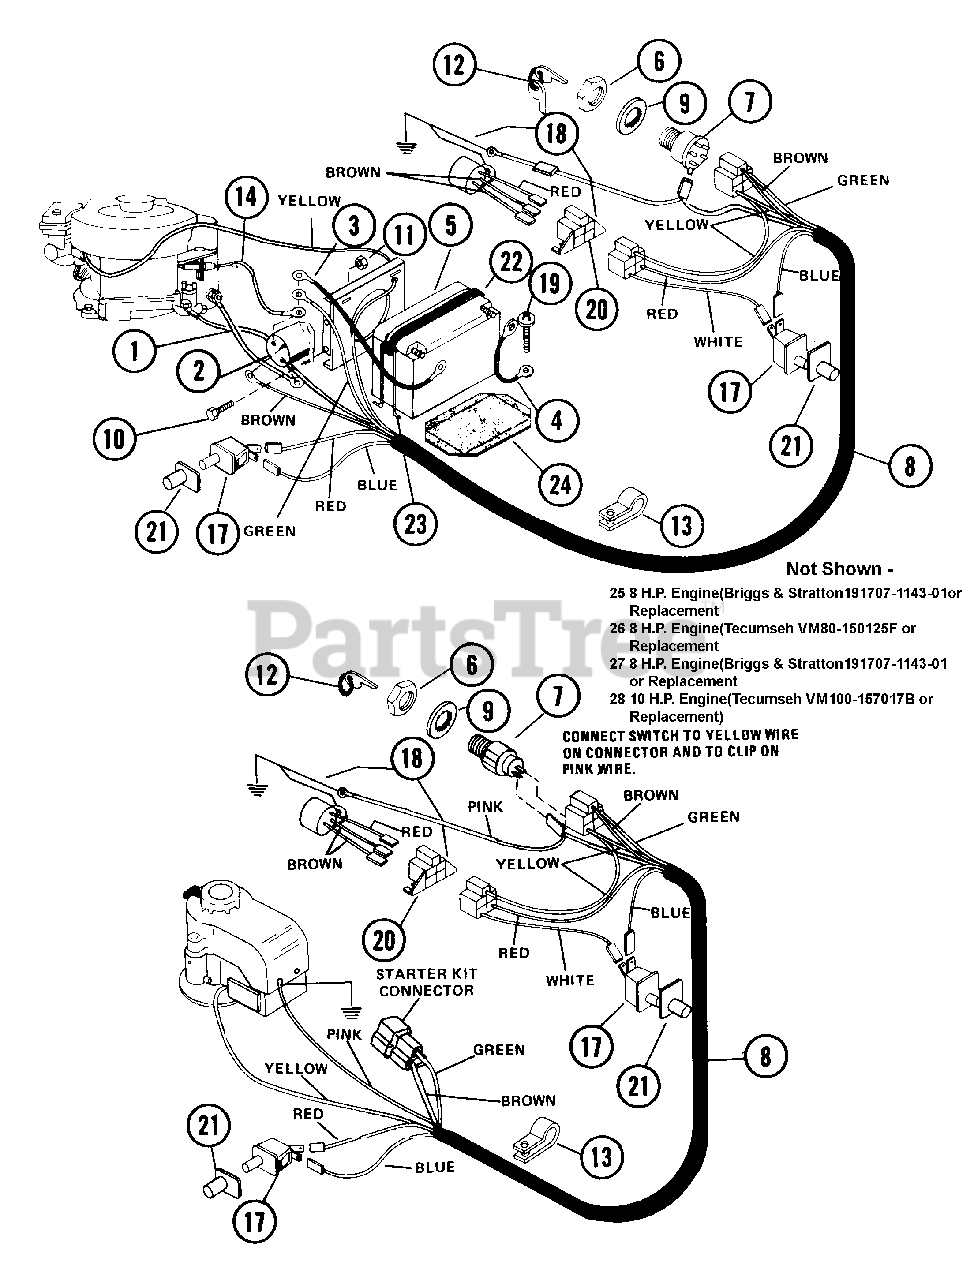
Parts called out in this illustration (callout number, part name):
1	GROUND CABLE .25X13.00X.31
2	SOLENOID,STARTER SWITCH
3	GROUND CABLE
4	GROUND WIRE
5	BATTERY
6	NUT .625-32 ALUM
7	IGNITION SWITCH ASSEMBLY
7	KEY SWITCH
8	WIRING HARNESS
8	WIRING HARNESS-B&S
9	WSHR-LK-INT .625X.045 PL
10	BLT-HEX .25-20X.50 PL GR2
11	NUT-LK-CTR .250-20 PL
12	KEYS
14	CHARGING WIRE
15	FUSE
18	MODULE T KIT
18	MODULE B KIT
19	SCR-TAP 10-24X.375 CRPH 1A
20	CONNECTOR
21	SCR-TAP 12-24X.50 HWH PL TR
22	BATTERY STRAP
23	HOOK
24	RUBBER PAD
25	8 H.P. Engine(Briggs & Stratton191707-1143-01 or Replacement)
26	8 H.P. Engine(Tecumseh VM80-150125F orReplacement)
27	8 H.P. Engine(Briggs & Stratton191707-1143-01 or Replacement)
28	10 H.P. Engine(Tecumseh VM100-157017B) orReplacement)
